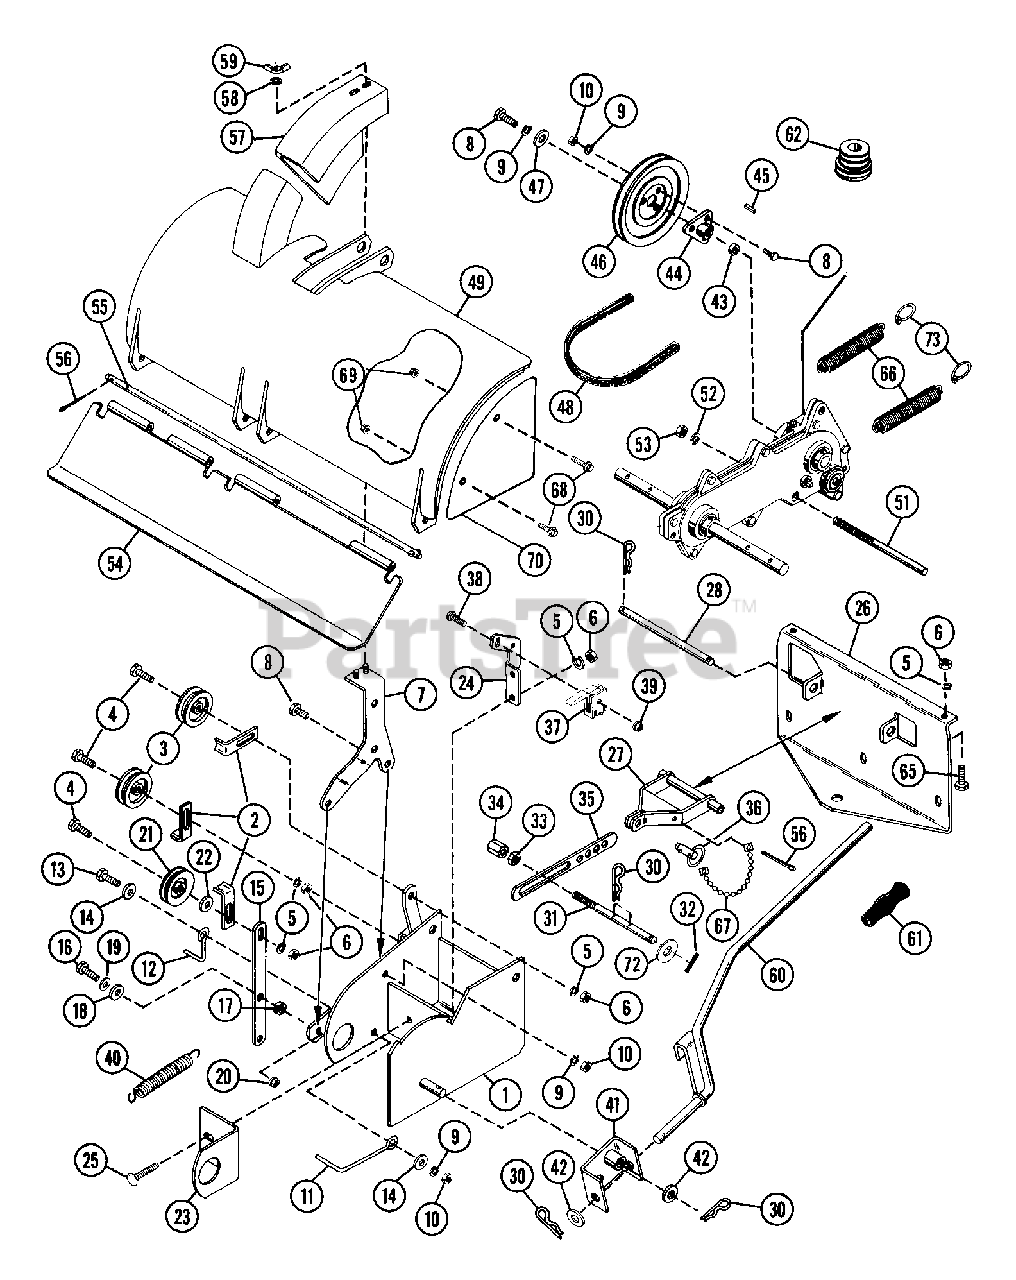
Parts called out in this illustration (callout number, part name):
1	FRAME
2	BELT FINGER
3	IDLER-FLAT 2.75 X .38 DAYCO
4	BLT-HEX .38-16X1.75 PL GR2
5	WSHR-LK .375X.115 HVY PL
6	NUT-HEX .375-16
7	BELT GUARD BRACKET
8	BLT-HEX .31-18X.75 PL GR5
9	WSHR-LK .312X.097 PL HVY
10	NUT-HEX .312-18
11	BELT FINGER
12	BELT FINGER
13	BLT-HEX .31-18X1.25 PL GR5
14	WSHR-FL-STL.344X.688X.065PL
15	CLUTCH BRACKET
16	BLT-HEX .31-18X1.00 PL GR5
17	SPACER BUSHING .5 X .32 X .21
18	WSHR-FL-STL .505X.875X.024 PL
19	WSHR-FL-STL .323X.625X.062 PL
20	NUT-FLG. .312-18 PL
21	IDLER-V 3.06 X .38
22	WSHR-FL-STL .382X.812X.062
23	CHAIN CASE MOUNTING BRACKET
24	SWITCH BRACKET
25	BLT-RDHDSQNK .38-16X1.0 GR5PL
26	TILLER HITCH PLATE
27	DEPTH CONTROL
28	MTG. PIN
30	PIN-HAIR INT .12X2.75
32	PIN-ROLL .125X1.00
33	NUT-JAM .50-13 PL
34	ADJUSTMENT ROD
35	DEPTH BAR
36	LATCH PIN
37	SWITCH INTERLOCK
38	SCR-MCH 10-24X1.00 SLRH PL
39	NUT-KEPS 10-24 PL
40	SG-TENS .091X.73X5.28 WLD 30
41	HANDLE PIVOT
42	WSHR-FL-STL .755X1.250X.125
43	SPACER .765X1.000X.781
44	HUB
45	KEY-SQ .188X.625X.188 SAE 61
46	PLY-V 9.0 X 1.25 3BLT
47	WSHR-FL-STL .328X1.0X.094
48	V-BELT, HA-WRAPPED
49	TINE HOOD ASSEMBLY
50	BLT-HEX .31-18X3.00 PL GR5
51	LIFT PIN
52	WSHR-LK .750X.188 MED PL
53	NUT-JAM .75-10 PL
54	TAIL BOARD
55	ROD - TAIL BOARD HINGE
56	PIN-COTR .09X.75 PL
58	WSHR-LK-EXT. 250 ID
59	NUT-WING .250-20 YWZC
60	LIFT HANDLE
62	TRIPLE GROOVE PULLEY
63	WIRE HARNESS
64	NUT-LK-CTR .375-16 GR A PL
65	BLT-HEX .38-16X1.00 PL GR5
66	SG-TENS .162X1.25X8.25 WLD 25
68	BLT-SERHFWH .31-18X.75 PL
69	NUT-FLG. .312-18 PL
70	SIDE PLATE
71	WIRE CLIP
72	WSHR-FL-STL .531X1.062X.095 PL
73	SPRING HOOK
